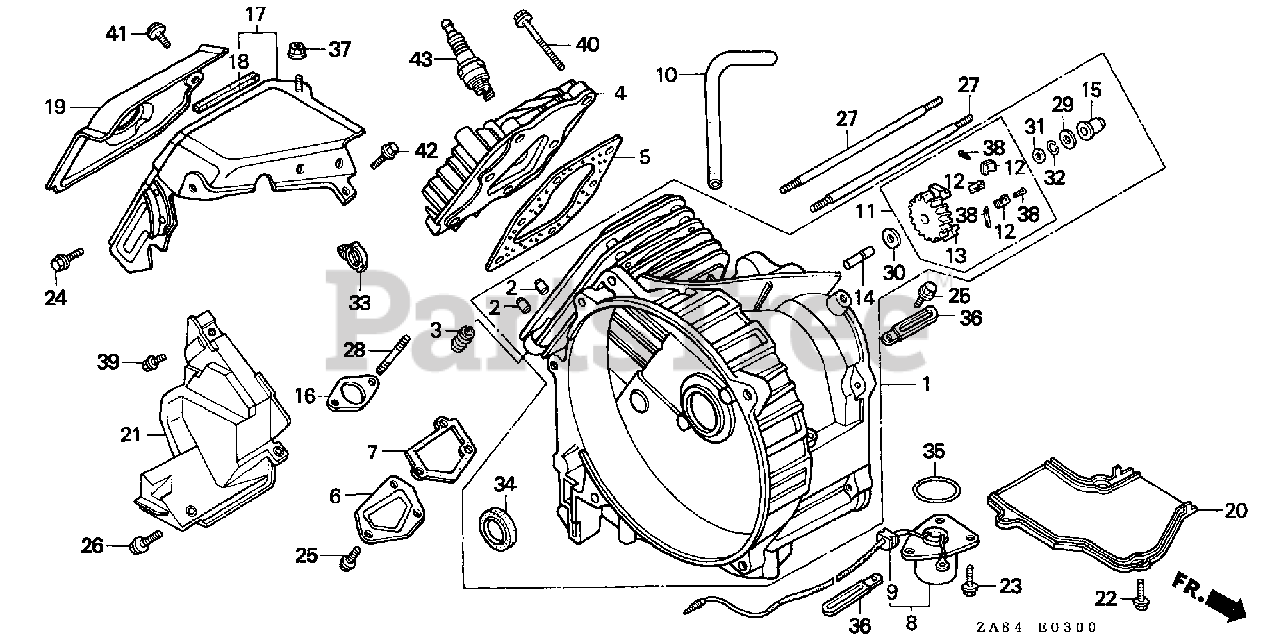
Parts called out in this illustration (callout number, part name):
1	CYLINDER ASSY. (010)
2	GUIDE, VALVE (OS)
2	GUIDE, VALVE Use up to Engine SN 1289751.
3	LINER, PORT
4	CYLINDER HEAD
5	GASKET, CYLINDER HEAD
6	COVER, TAPPET ROOM
7	GASKET, TAPPET COVER
8	SWITCH, OIL LEVEL
9	GROMMET, WIRE
10	TUBE, BREATHER
11	HOLDER, GOVERNOR
12	WEIGHT, GOVERNOR
13	GEAR, GOVERNOR HOLDER
14	SHAFT, GOVERNOR HOLDER
15	SLIDER, GOVERNOR
16	GASKET, MUFFLER
17	SHROUD ASSY.
18	SEAL, SHROUD
19	COVER, TOP
20	GUIDE, AIR
21	SEPARATOR, EX. PIPE
22	BOLT, FLANGE (5X12)
23	BOLT, FLANGE (5X14)
24	BOLT, FLANGE (6X12) (CT200)
25	BOLT, FLANGE (5X10)
26	BOLT, FLANGE (6X16)
27	BOLT, STUD (6X116)
28	BOLT, STUD (6X28)
29	WASHER (5.2X17)
30	WASHER (5.2X13)
31	WASHER (5.2X9)
32	CLIP, GOVERNOR HOLDER
33	CLIP, WIRE HARNESS (8MM) *NH1* (BLACK)
34	OIL SEAL (17X30X6) (NOK)
35	O-RING (34.6X2.5)
37	NUT, FLANGE (6MM)
38	PIN, COTTER (2.0X12)
38	PIN, COTTER (2.0X15)
39	BOLT, FLANGE (6X10)
40	BOLT, FLANGE (6X35)
41	BOLT, FLANGE (6X10)
42	BOLT, FLANGE (6X18)
43	SPARK PLUG (BMR4A) (NGK)
43	SPARK PLUG (W14MR-U) (DENSO)
